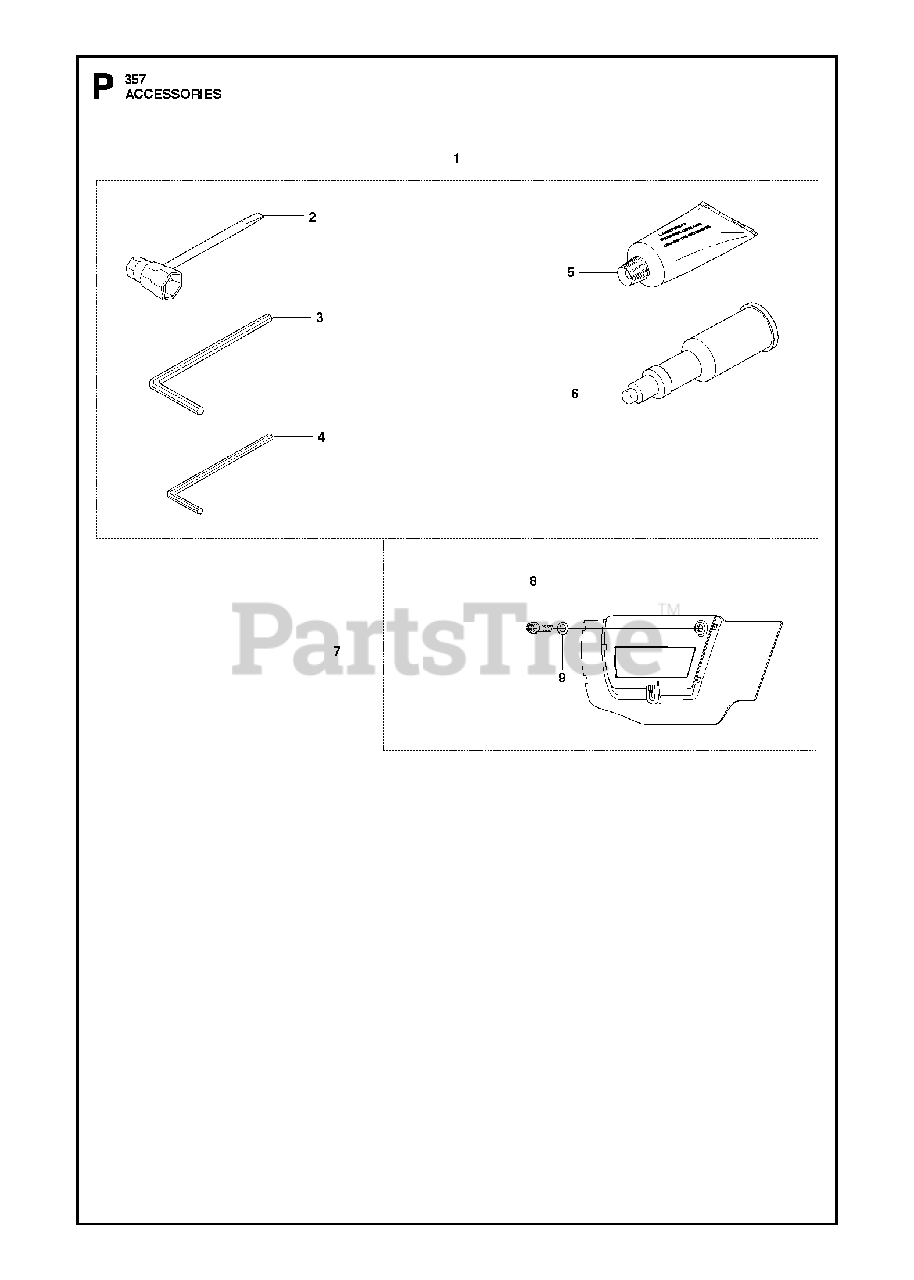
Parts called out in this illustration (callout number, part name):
1	TOOL KIT
2	COMBI TOOL
3	L-SPANNER
4	L-SPANNER
5	GREASE
6	Grease Gun
7	PROTECTOR
8	SCREW
9	O-RING
